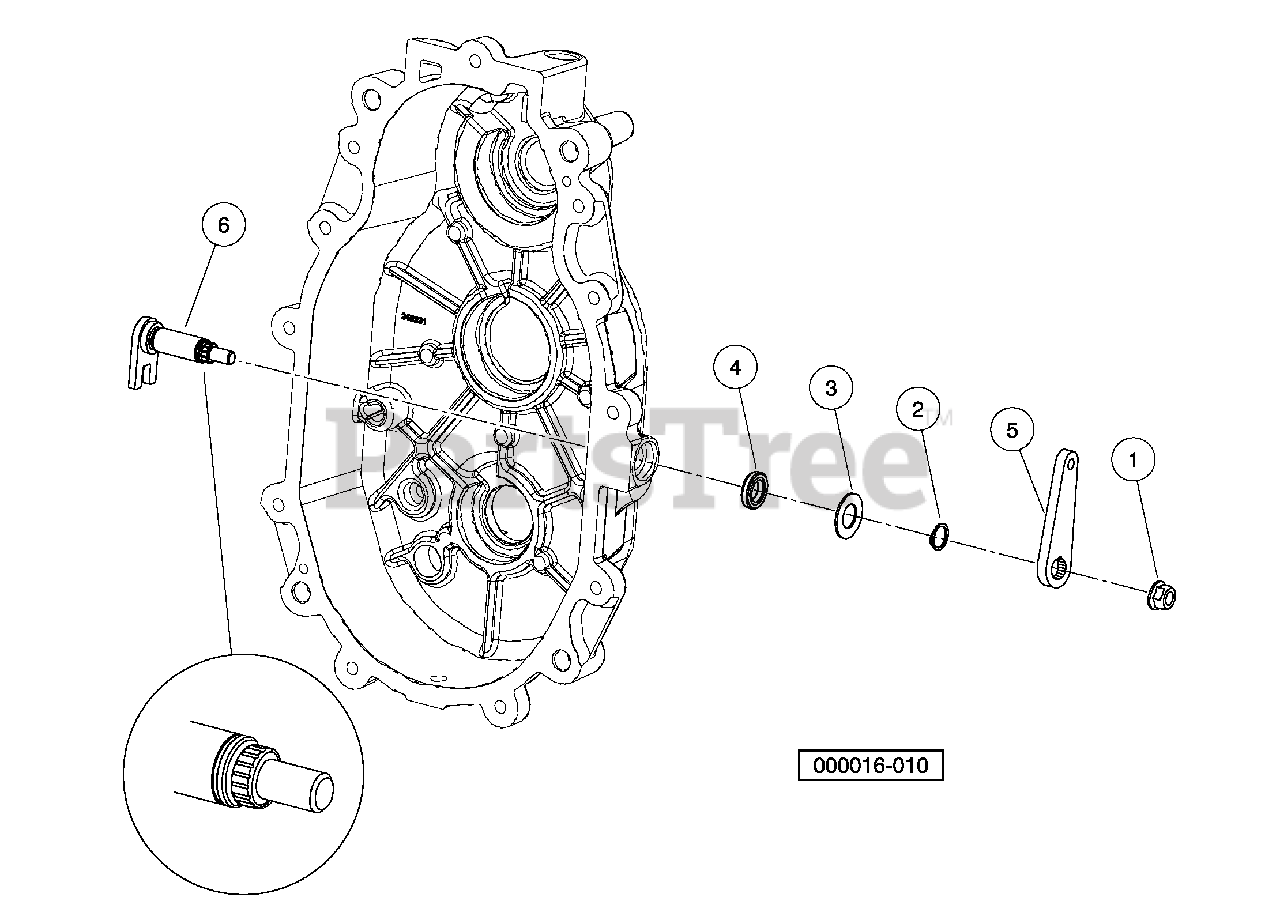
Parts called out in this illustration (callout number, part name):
1	Nut, Lock Hex, Nylon, 5/16-24
2	Ring, Retaining, External 9/16
3	Washer, Flat, .58 X 1.08 X .05
4	Seal, Dul Lip, .88 X .56 X .19
5	Bellcrank, Alum
6	Shaft, Shift
